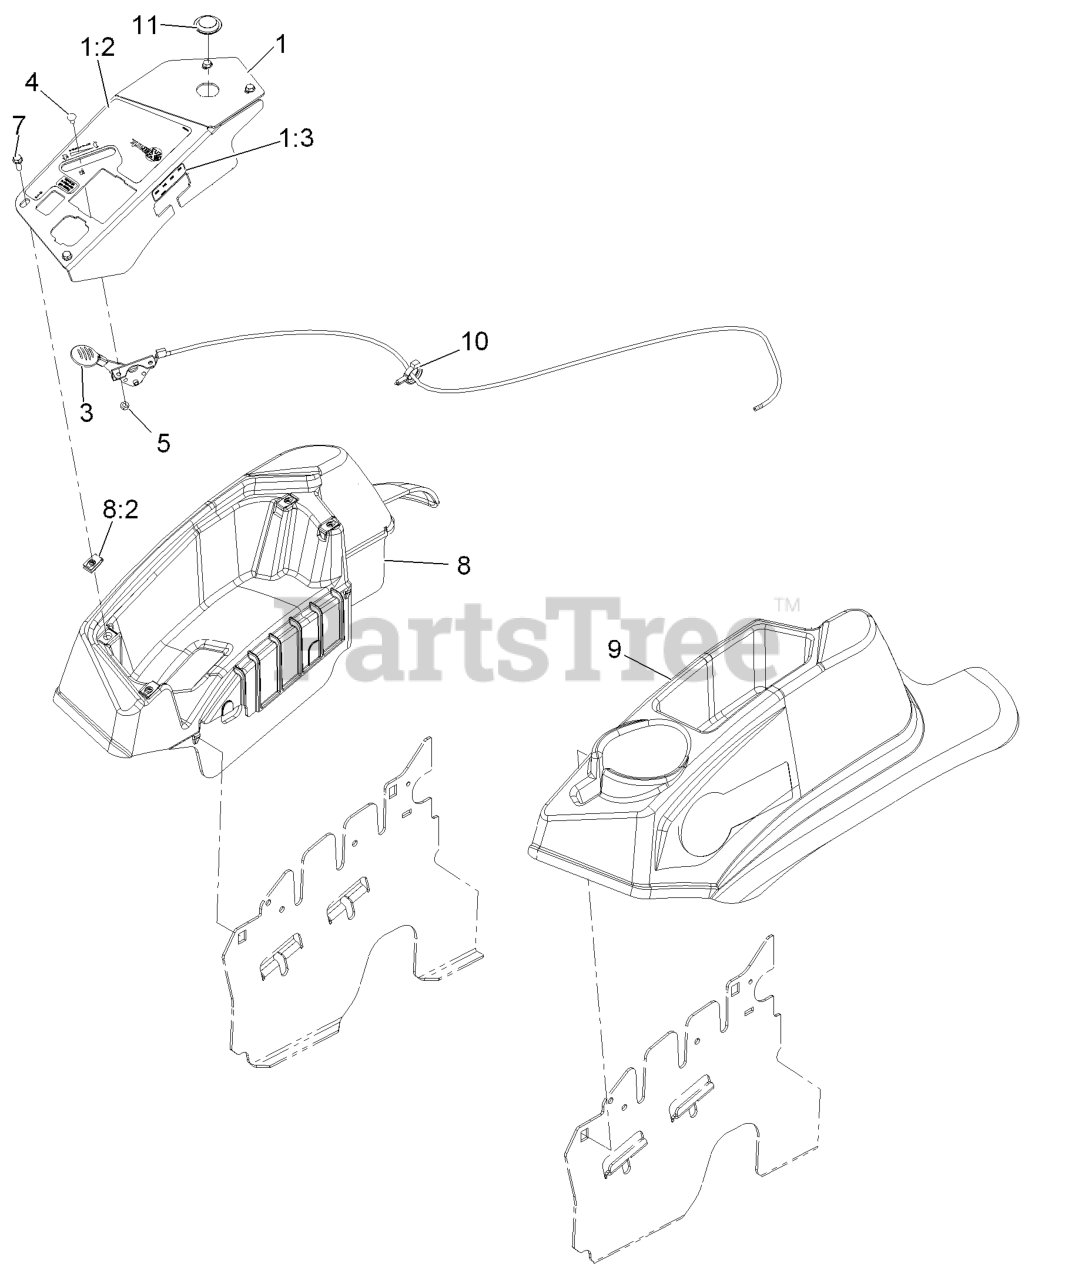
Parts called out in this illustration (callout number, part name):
1	CONTROL PANEL W/DECALS AS
1:2	DECAL,CONTROL PANEL LP
1:3	DECAL-FUSE
3	ASM,THROTTLE CABLE
4	BOLT-CARR
5	NUT-LOCK, NI
7	SCREW-HWH
8	CONSOLE,RH AS ASM
8:2	Nut-Retainer-Panel 1/4-20
9	CONSOLE, LH AS
10	CLAMP-HOSE
11	PLUG-PLASTIC
